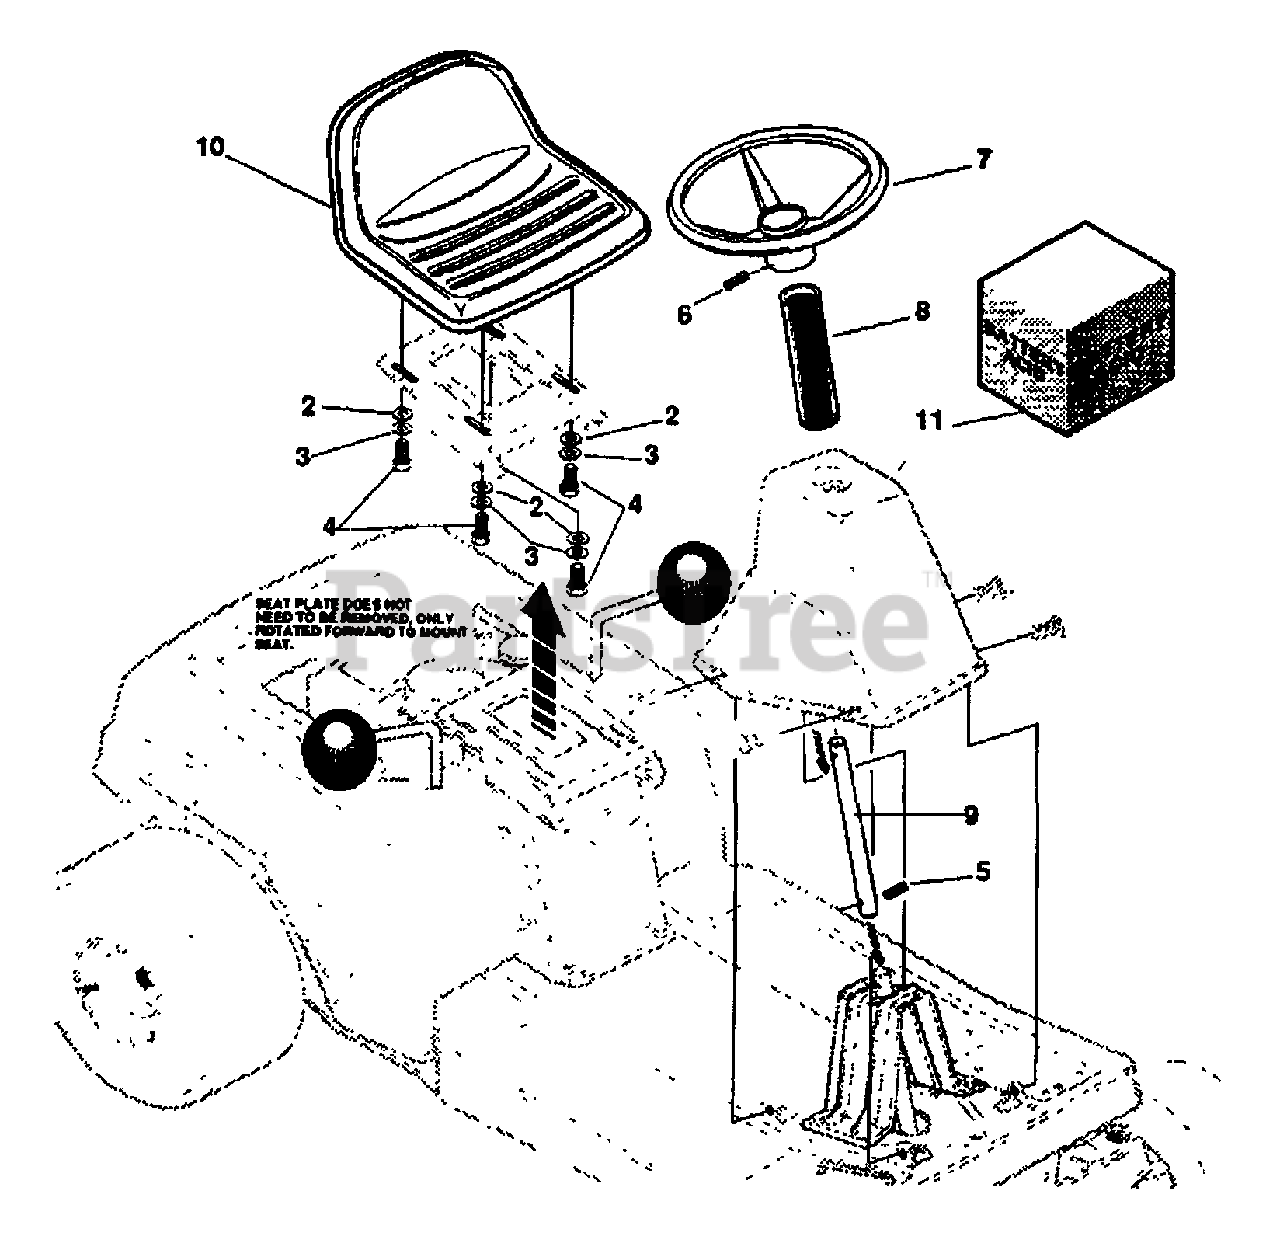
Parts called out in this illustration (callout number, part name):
2	WASHER, FLAT.344 X .69 X .065
3	WASHER, HV SPT LK .32 8 X .60 X .11
4	SCREW, 5/16-18 X .75 HHC GR2
5	PIN, SPRING .187 DIA X 1.25 LG MD
6	PIN, SPRING .250 DIA X 2.25 LG HVPL
7	WHEEL, STEERING
8	TUBE, DECORATIVE
9	TUBE-STEERlNG
11	ACID PACK, 32 OZ.
